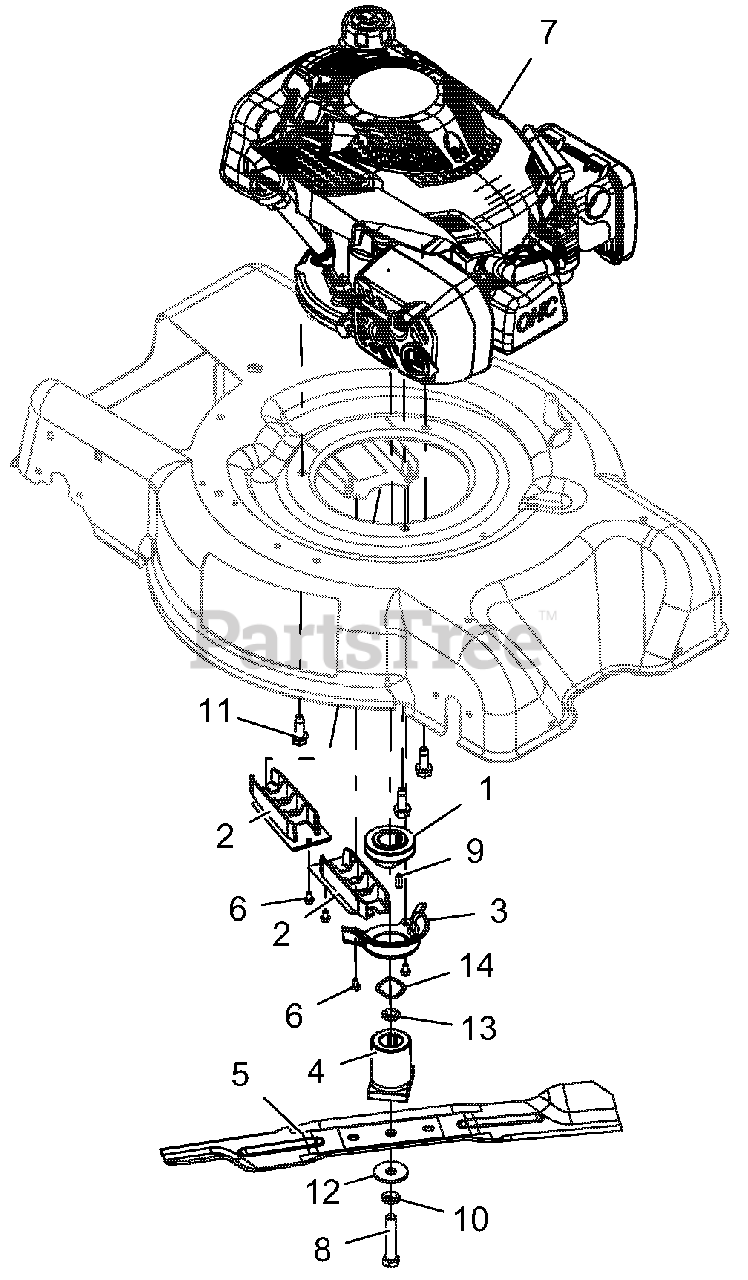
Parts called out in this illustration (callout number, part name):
1	PULLEY, GROUND DRIVE, LM
2	GUIDE, BELT INNER
3	GUIDE, BELT CRANKSHAFT
4	ADAPTOR, BLADE
5	BLADE, MOWER 21" HIGH-LIFT
6	SCR, TAP 10-24X.375 PRE-COAT 80
7	ENGINE, SUBARU
8	BLT-HEX .44-20X2.25 GR8 YWZC
9	KEY-SQ .188X.188X.625
10	WSHR-LK .44X.109 REG YWZC
11	SCR-TAP .38-16X1.00 HWH TR YZ
12	WSHR-FL-STL .4375X1.50X.125 YWZC
13	WSHR-FL-STL .459X.750X.105 YWZC
14	WASHER, WAVE
